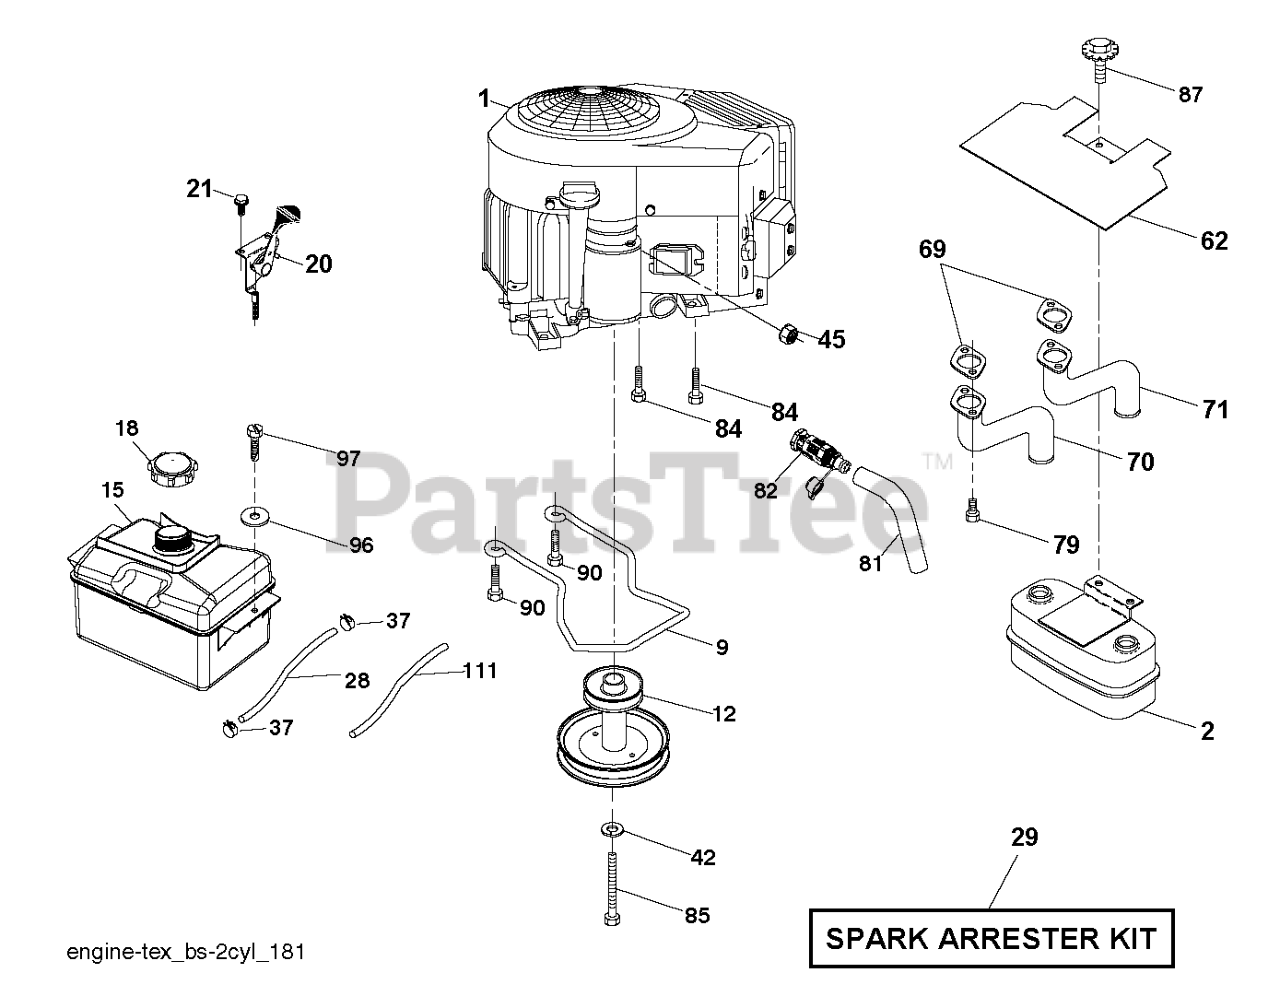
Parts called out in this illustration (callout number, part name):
2	MUFFLER.ASM.TWIN.MNTG.BRACKET
9	KEEPER.BELT.ENG.4.25"2.BLT.431
12	ENGINE.PULLEY
18	CAP.FUEL.2 WAY VENT
20	CONTROL.TH/CK.COBRA.B&S.TWN.BK
28	LINE.FUEL.20"FRONT.EMI
29	KIT.SPARK ARRESTOR 794945 B&S
37	HOSE CLAMP
62	SHIELD.HEAT.MUFFLER
69	GASKET.MUFFLER
70	EXHAUST.TUBE.LH.BS/TWIN
71	EXHAUST.TUBE.RH.B&S.TWIN.INTEK
81	TUBE, DRAIN OIL ASM.
82	VALUE.OIL.DRAIN
84	SCREW.3/8-16
85	BOLT.HEX.7/16-20X4.GR5.1.5BLUE
87	BOLT.5/16-18UNCX1.W/SEMS.BLK
90	SCREW 3/8-16X1
97	SCREW HEXWSHR 1/4-20X3/4
111	TUBE.PURGE.FUEL.1875
